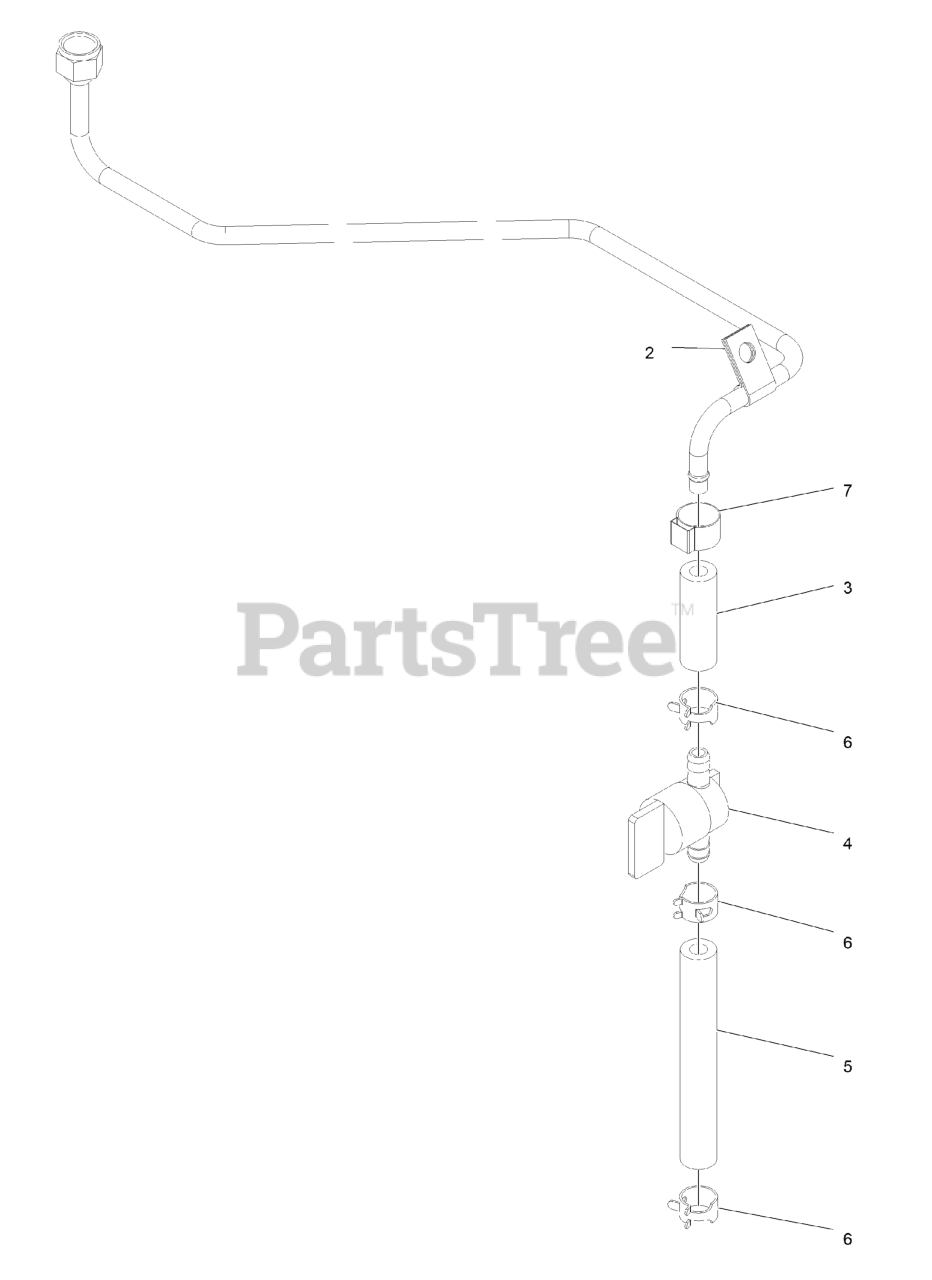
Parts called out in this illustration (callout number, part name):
2	CLIP-CLOSED, INSULATED
3	Hose-Fuel
4	VALVE-FUEL
5	HOSE-FUEL
6	CLAMP-HOSE
7	Clamp-Hose, Fuel
